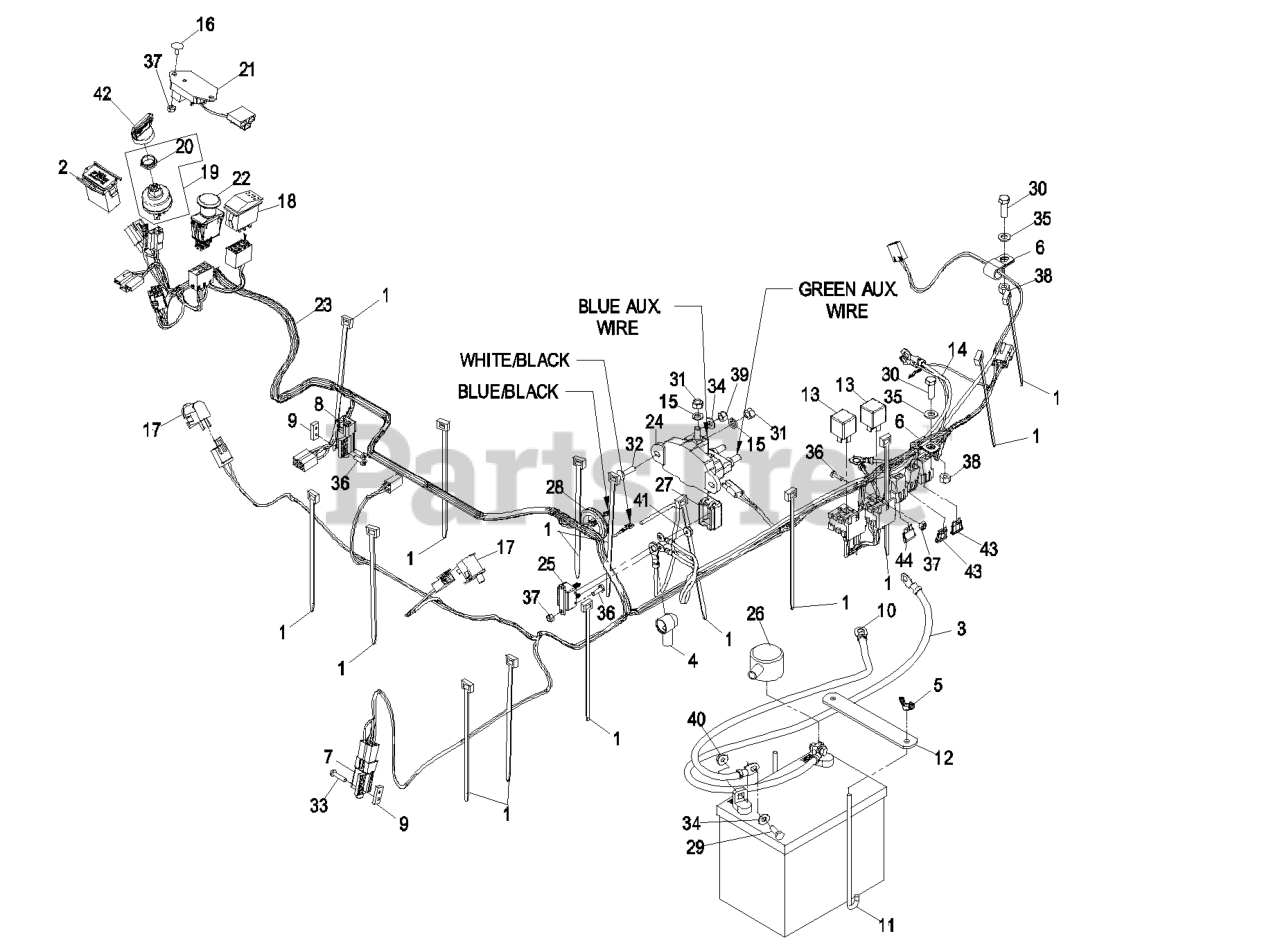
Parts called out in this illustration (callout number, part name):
1	TIE-PLASTIC
2	METER-HOUR
3	ASM,POSITIVE BATTERY CABL
4	INSULATOR-SOLENOID
5	WINGNUT
6	CLIP-LOOM
7	SWITCH-BRAKE
9	PLATE-TAPPED
10	WIRE-GROUND
11	BOLT-HOLDDOWN
12	STRAP-HOLDDOWN, BATTERY
13	RELAY
14	HARNESS,AUX HYDRAULICS
15	WASHER-LOCK
16	BOLT-CARR
17	SWITCH-BAIL
18	SWITCH,ROCKER (ON)-NONE-(
19	ASM,SWITCH W/NUT
20	NUT-SWITCH, IGNITION
21	MODULE-DELAY, SEAT
22	SWITCH-PTO
23	HARNESS,WIRING FMZ KOHLER
24	CONTACTOR, REVERSING POLA
25	CIRCUIT BREAKER,40A
26	INSULATOR-BATTERY
27	COVER,CIRCUIT BREAKER
28	GROMMET-RUBBER
29	SCREW-HH
30	SCREW-HH
31	NUT-HEX
32	SCREW-CARR
33	SCREW-PPH
34	WASHER-FLAT
35	WASHER-PLAIN
36	SCREW-PPH
37	NUT-LOCK, NI
38	NUT-LOCK, NI
39	NUT-LOCK, NI
41	NUT-KEPS
42	KEY-IGNITION
43	FUSE-BLADE TYPE, 20 AMP
44	FUSE-BLADE, 15 AMP
45	FUSE-BLADE TYPE, 30 AMP
